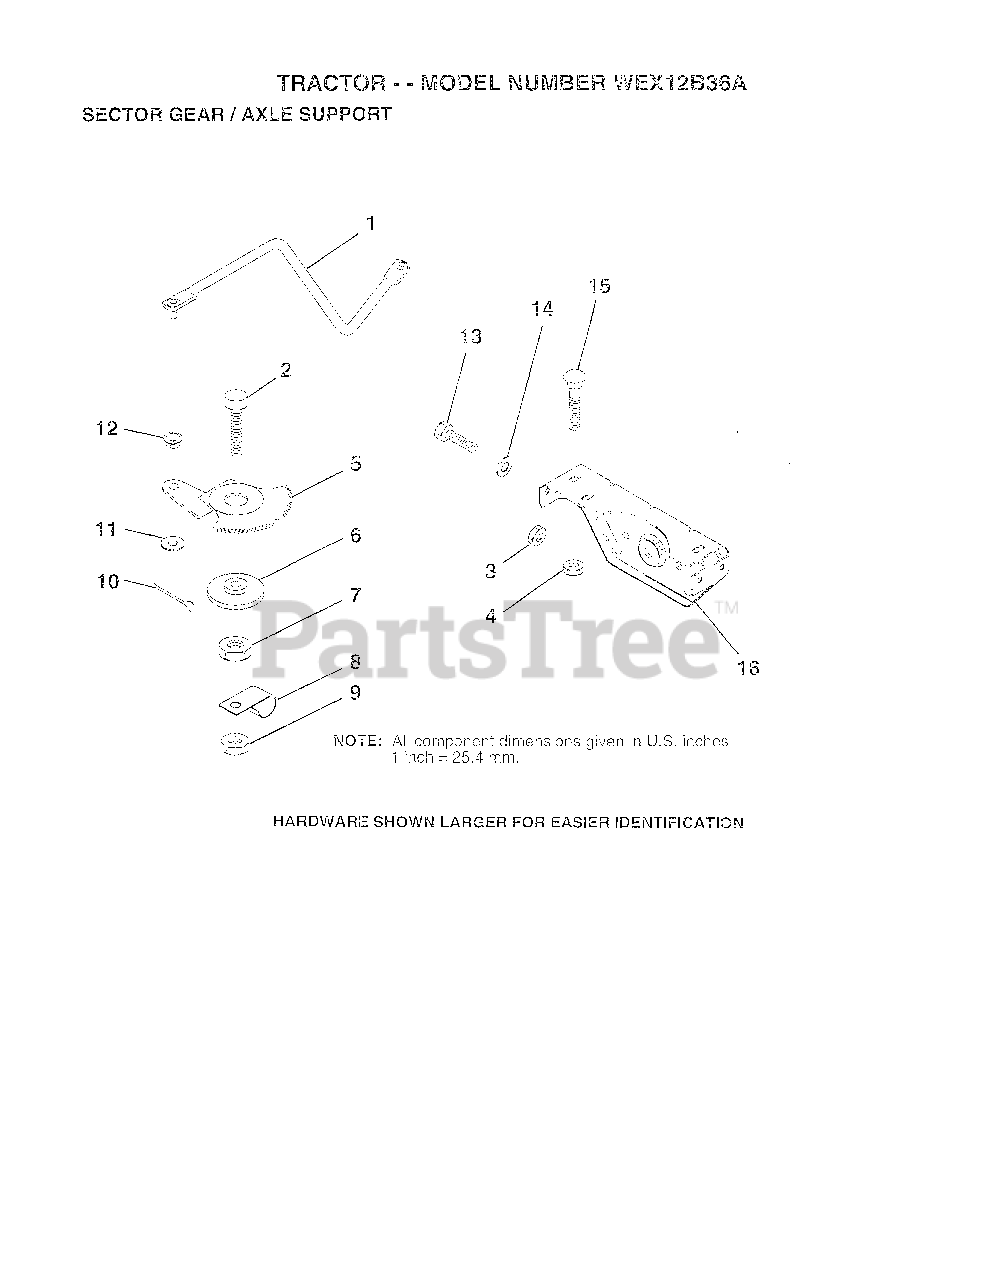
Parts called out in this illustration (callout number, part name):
1	DRAG LINK
2	"BOLT,HEX"
5	GEAR SECTOR
6	BUSHING
7	NUT
8	CLIP INSULATOR
9	NUT LTV
10	COTTER PIN
11	WASHER
12	BUSHING.DRAGLINK
13	BOLT
14	WASHER
15	BOLT
16	SUPT AXLE FRONT
